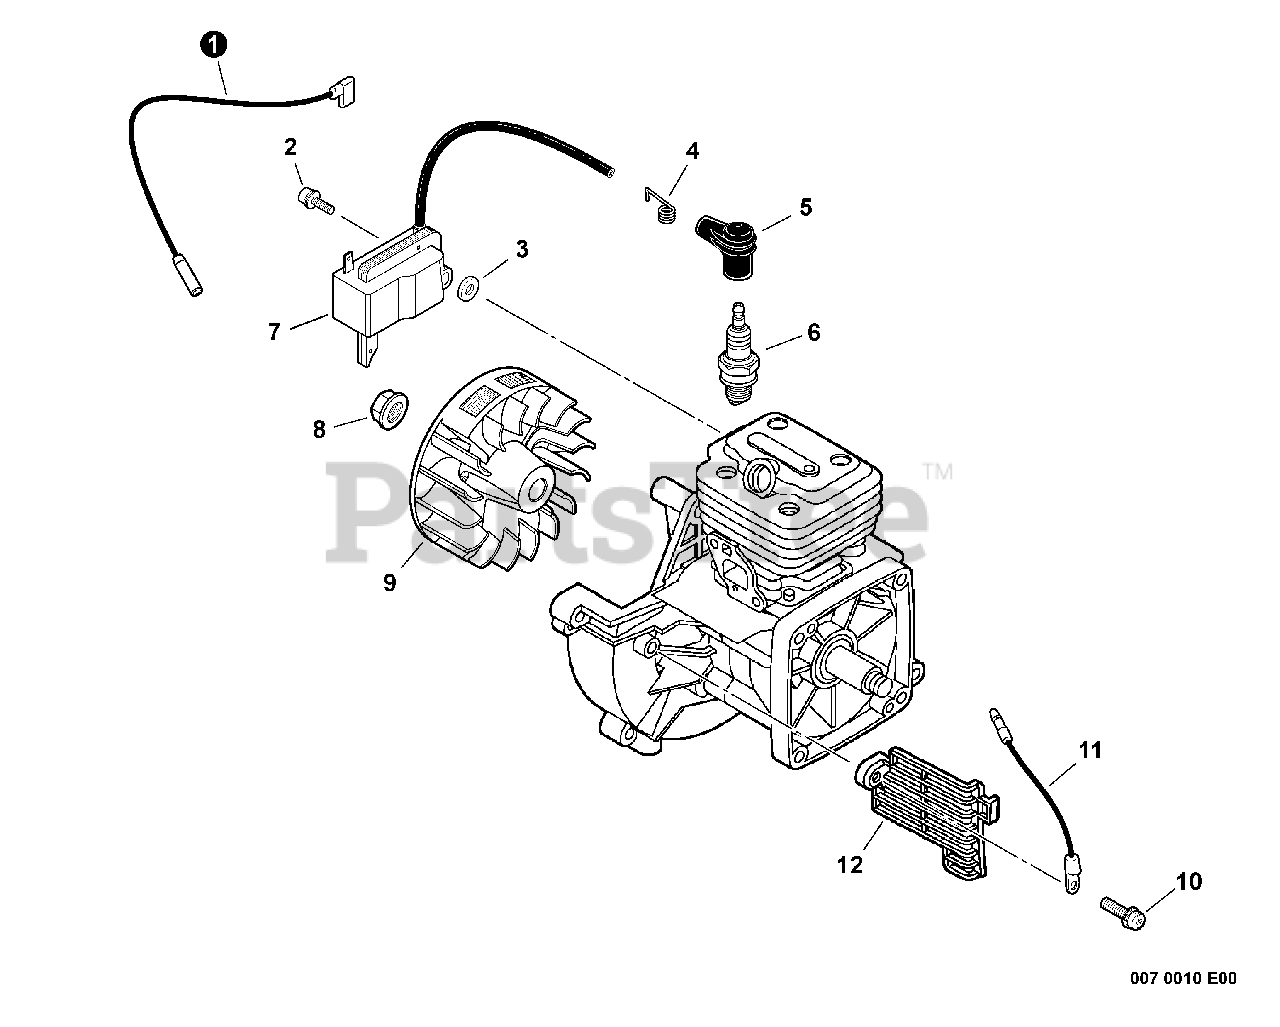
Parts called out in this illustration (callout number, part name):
1	LEAD - IGNITION
2	BOLT 5×20
3	SPACER 5
4	TERMINAL, SPARK PLUG
5	CAP, SPARK PLUG
6	SPARK PLUG - BPMR8Y
7	COIL, IGNITION
8	NUT, FLANGE M8
9	FLYWHEEL
10	SCREW 5×10
11	LEAD - GROUND L= 115
12	SHIELD, DEBRIS
